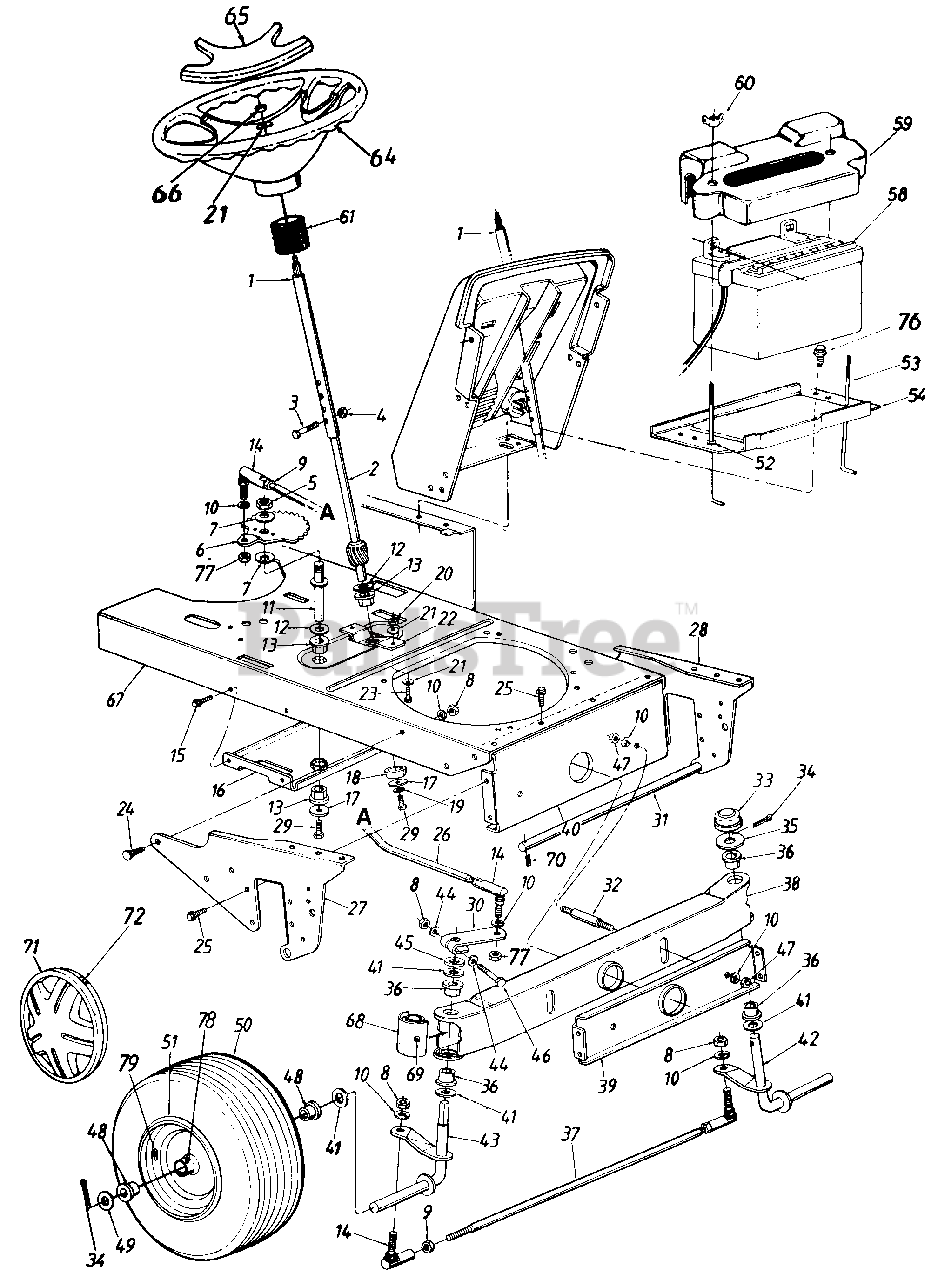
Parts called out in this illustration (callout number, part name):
1	Steering Column Ass'y.
2	Lower Steering Shaft
3	Hex Bolt 1/4-20 x 1.31" Lg.
4	Hex L-Nut 1/4-20 Thd.
5	Hex Nut 5/8-18 Thd.
6	Steering Gear Segment
7	Bell-Wash. 5/8" I.D. x 1.25" O.D.
8	Hex Nut 3/8-24 Thd.
9	Hex Jam Nut 3/8-24 Thd.
10	L-Wash. 3/8" I.D.
11	Steering Gear Segment Shaft
12	Fl-Wash. .64" I.D. x 1.24" O.D.
13	Hex Flange Brg. .63" I.D.
14	Ball Joint Ass'y.
15	Hex Wash. Hd. TT-Tap Scr. 1/4-20 x .5" Lg.
16	Deck Idler Support Brkt.
17	Fl-Wash. .33" I.D. x 1.25" O.D.
18	Spacer .985" I.D. x 1.25" O.D.
19	L-Wash. 5/16" I.D.
20	Hex Nut 5/16-24 Thd.
21	Bell-Wash. .345" I.D. x .88" O.D.
24	Ribbed Neck Bolt 3/8-24 x .8" Lg.
25	Hex Wash. TT-Tap Scr. 5/16-18 x .62" Lg.
26	Steering Drag Link
27	Pivot Bar Side Plate - R.H.
28	Pivot Bar Side Plate - L.H.
29	Hex Bolt 5/16-18 x .62" Lg.
30	Steering Arm
31	Deck Connecting Rod
32	Pivot Bar Shld. Bolt 3/8-16 x 5/8" Lg.
33	Cap
34	Cotter Pin 5/32" Dia.
36	Flange Brg. .757" I.D.
37	Tie Rod 20.25" Lg.
38	Pivot Bar Assy.
41	Fl-Wash. .76" I.D. x 1.49" O.D.
42	Front Axle Ass'y. - L.H.
43	Front Axle Ass'y. - R.H.
44	Bowed Washer
45	Spacer .755" I.D. x 1.25" O.D.
46	Hex Bolt 3/8-24 x 2.25" Lg.
47	Hex Nut 3/8-16 Thd.
48	Ball Brg. .75" I.D.
49	Fl-Wash. .71" I.D. x 1.5" O.D.
50	Wheel Ass'y. Comp.
51	Rim Only
52	Push Nut
53	Battery Hold Down Rod
54	Battery Plate
58	Battery (275 Cold Crank Amps)
59	Battery Cover
60	Wing Nut Plastic 1/4-20 Thd.
61	Steering Bellow
64	Steering Wheel
65	Steering Wheel Insert
66	Hex L-Nut 5/16-24 Thd.
67	Lower Frame
68	Pivot Bar End Cap
69	Grease Fitting
70	Internal Cotter Pin
71	Hub Cap
72	Spring Clip
76	Hex AB-Tap Scr. 1/4 x .62" Lg.
77	Hex Jam L-Nut 3/8-24 Thd.
78	Grease Fitting
79	Air Valve
